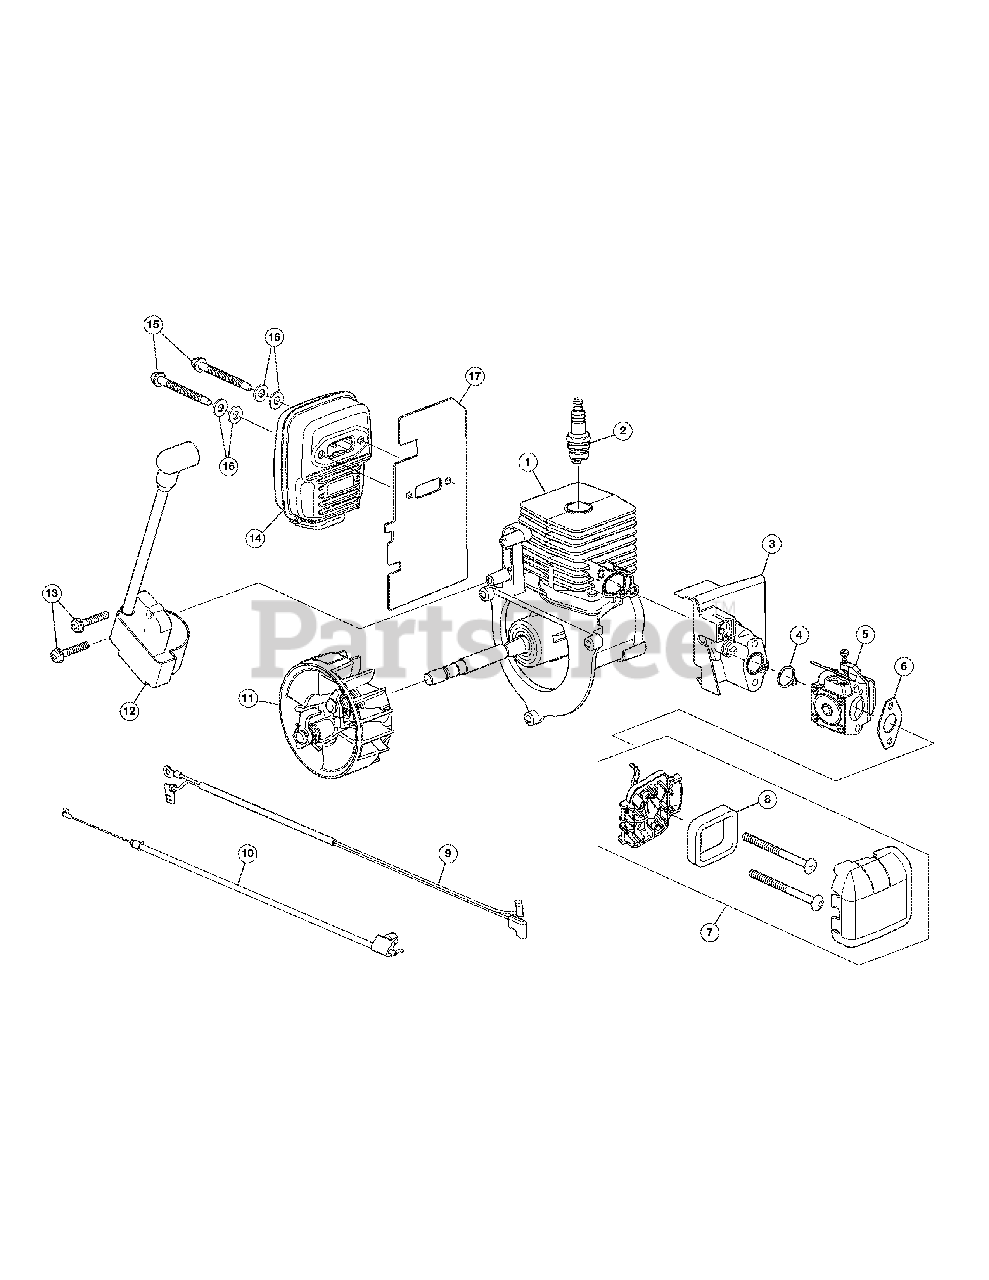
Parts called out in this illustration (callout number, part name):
1	Shortblock Assembly
2	Spark Plug
3	Insulator Assembly (Incl. 4)
4	O-Ring
5	Carburetor
6	Carburetor Gasket
7	Air Cleaner Assembly (Incl. 8)
8	Air Cleaner Filter
9	Lead Wire
10	Throttle Cable
11	Flywheel Assembly
12	Module Assembly (Incl. 13)
14	Muffler Assembly (Incl. 15, 16 and 17)
15	Muffler Screws
16	Washers
17	Muffler Gasket
